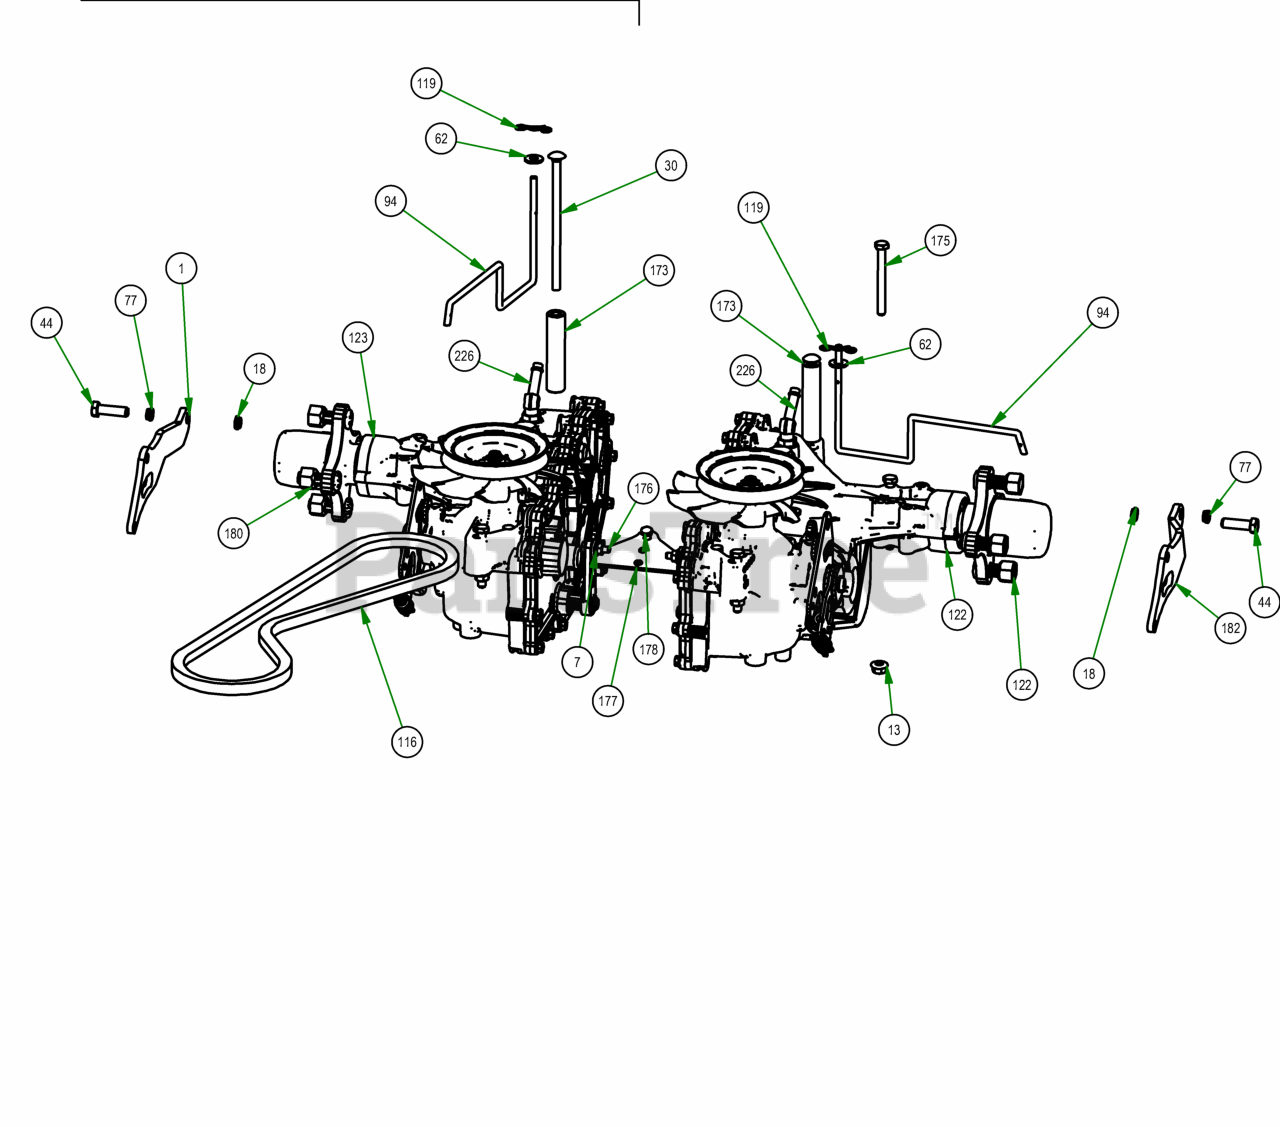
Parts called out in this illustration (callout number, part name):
1	SD Control Arm Plate RH
7	1/4-20 NYL INSERT FLANGE LOCKNUT ZINC
10	3/8-16 Nylon Insert Flange Locknut
13	5/16-18 NYLON INSERT FLANGE LOCKNUT ZINC
18	5/16-18 Nylock Insert Jam Locknut
30	5/16-18 X 6 CARRIAGE BOLT (GR.5) ZINC
44	3/8-16 X 1-1/4 HEX CAP SCREW (GR.5) ZINC
62	1/4 USS FLAT WASHER (3/4 OD) ZINC
77	Drive Arm Transaxle Spacer
94	2019 Stand On Neutral Rod
116	2020 Renegade Pump Belt, 42.99"
122	ZK-MMBC-SBKC-1PXX
123	ZK-JMBC-SBKB-1PXX
172	5/16-18 X 2-1/2 HEX CAP SCREW (GR.5) ZINC
173	2017 Transaxle Spacer
174	3/8-16 X 2 HEX CAP SCREW (GR.5) ZINC
175	5/16-18 X 3 HEX CAP SCREW (GR.5) ZINC
176	1/4-20 X 1 HEX CAP SCREW (GR.5) ZINC
177	2020 36" Brake Bracket 2020 36" Stand On
178	1/4-20 X 3/4 HEX CAP SCREW (GR.5) ZINC
179	1/4-20 NYLON INSERT LOCKNUT ZINC
180	Acorn Lug Nut
182	SD Control Arm Plate LH
226	ZT Fitting, 3/8 x 3/8 45 Degree, 4603-6-6
